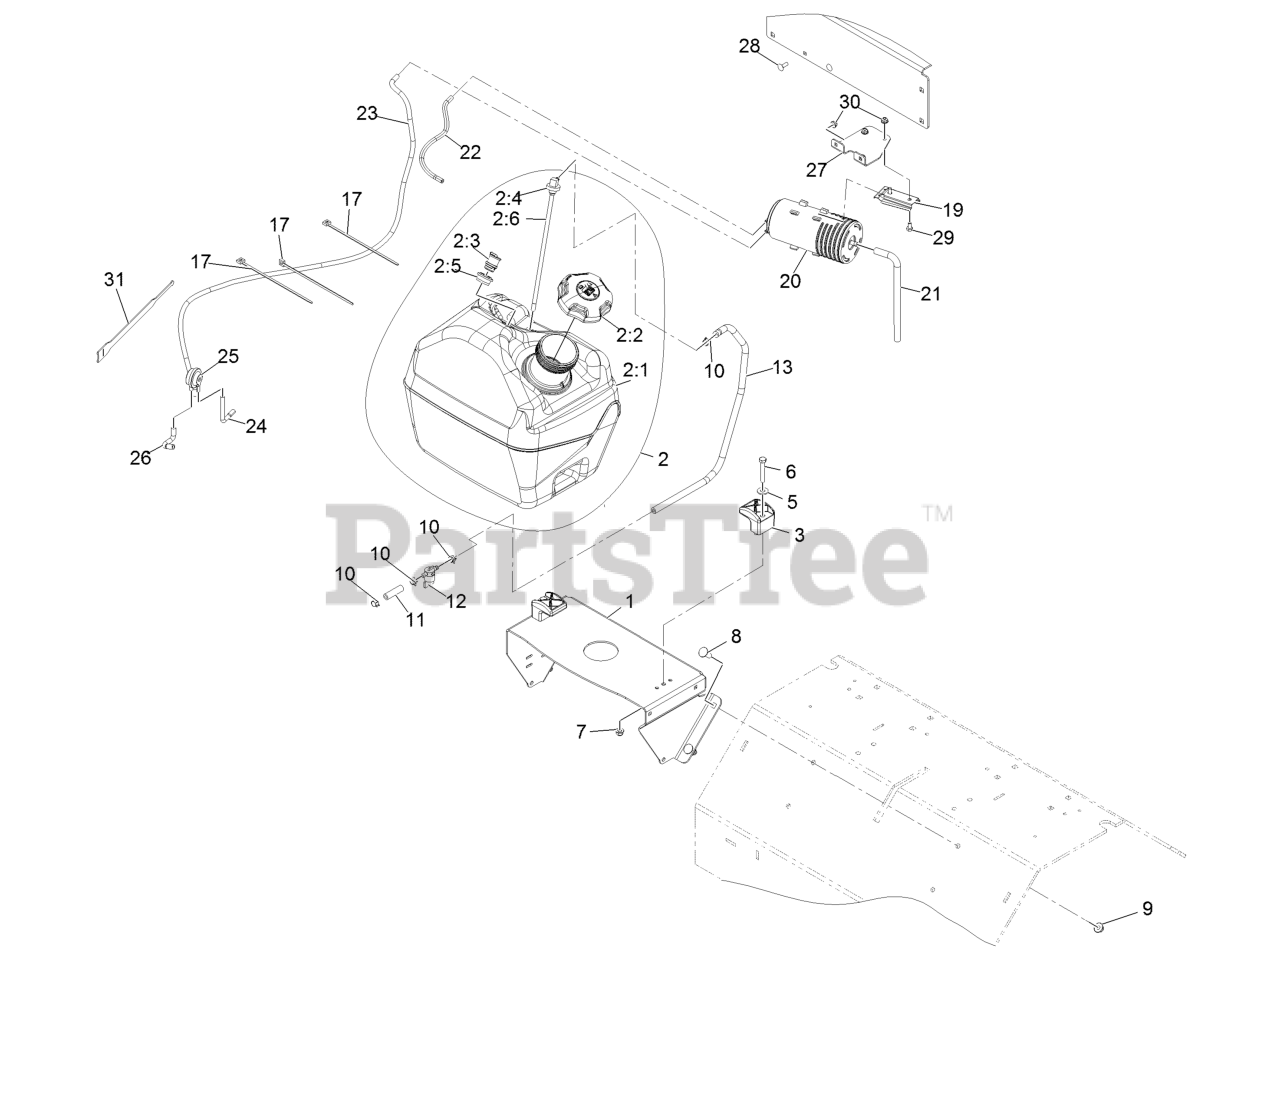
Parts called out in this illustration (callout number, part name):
1	Support-Tank, Fuel
2	Fuel Tank ASM
2:1	Tank-Fuel 5 Gal
2:2	Cap-Fuel, Ratcheting (3.5 Inch)
2:3	Grommet
2:4	Valve-Vent, Fuel
2:5	Bushing
2:6	Fitting-Fuel (W/Line And Screen)
5	Washer-5/16 Std
6	Screw-HH 5/16-18 X 2
7	Nut-Nyloc 5/16-18 Flg
8	Bolt-Carriage 3/8-16 X 1
9	Nut-Nyloc 3/8-16 Flg
10	Clamp-Hose
11	Hose-Fuel
12	Valve-Fuel
13	Hose-Line, Gas
17	Tie-Cable 7 15/16 (Large)
19	Bracket-Canister, Carbon
20	Canister-Carbon, 800Cc
21	Hose-Vent, Canister
22	Hose-Emissions
23	Hose-Vent, Formed
24	Hose-Vent, Formed
25	Valve-Control, Vacuum
26	Hose-Vent, Formed
27	Bracket-Mounting, Canister
28	Bolt-Carriage 1/4-20 X 3/4
29	Screw-HH 1/4-20 X 1/2
30	Nut-Nyloc 1/4-20 Flg
31	Strap-Velcro, Cable Tie
